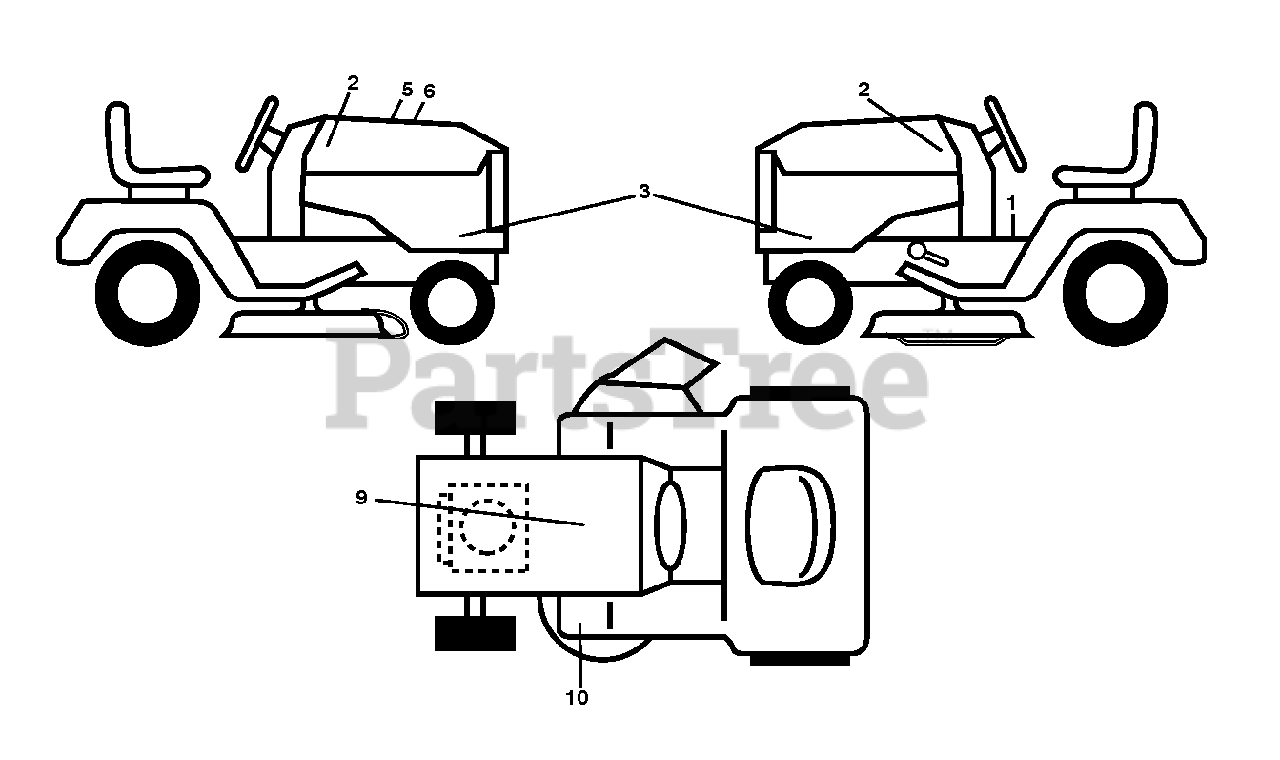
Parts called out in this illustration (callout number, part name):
1	DECAL.FENDER.WARNING
2	RP.DECAL.BADGE.170MM.TEXTLOGO
3	DECAL SDPL.HUSQGT2.YTHV42LS422
4	DECAL, NO STEP
5	DECAL.WARNING.CUST.RESP.E85.
6	DECAL.REPL.960430115.YTH22V42L
7	DECAL, CAUTION
8	DECAL.MOWER.SCH.48/54
9	DECAL BTRY SYMBOLS
10	DECAL.PEDAL.HUSQ.CROWN
